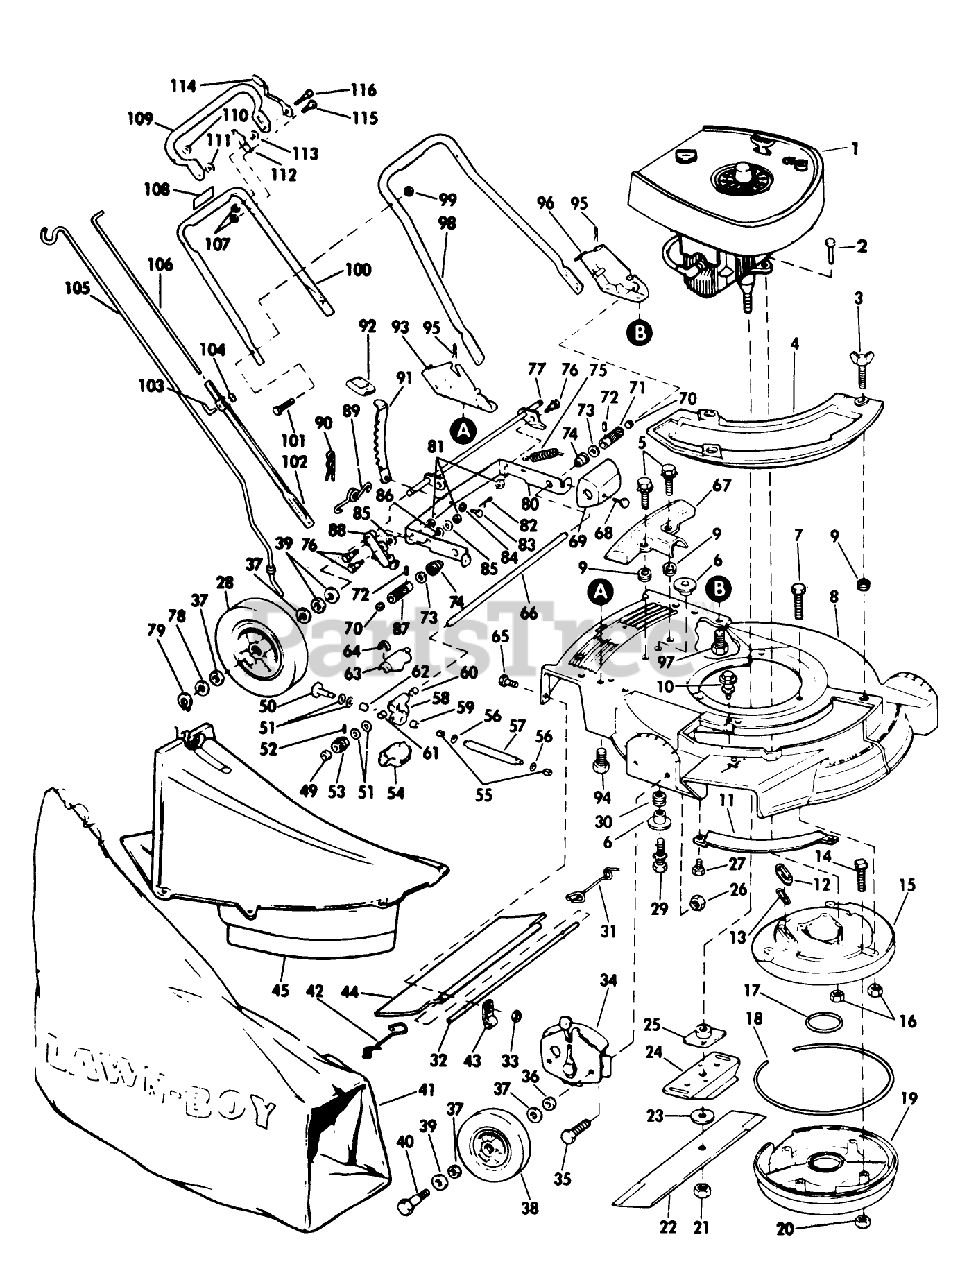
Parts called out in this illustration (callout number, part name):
2	BOLT F
3	WING SCREW LAWRE
5	SCREW SEMS TRM HEX HD
6	SPACER ECK PRES
7	SCREW V
11	BAR-TOE
12	SLEEVE
13	GASKET S
14	SCREW
16	NUT-LOCK F
18	Gasket Muffler (outside)
20	LOCKNUT E
21	NUT-BLADE
23	WASHER
25	PLATE AND COLLAR ASM
26	NUT-LOCK F
30	GROMMET
31	SPRIG T/SHLD ASOC
32	ROD 21" ADVANCE
33	LOCKNUT E
36	WASHER WROUGHT
37	WASHER
38	WHEEL & TIRE KIT
39	SPACER
40	BOLT WHEEL
41	89802 LB WHOLE GOODS
42	SPRING;TRAILING SHIELD RH
43	CLAMP ROD KMC
49	WASHER
51	THRUST WASHER
52	ROLL PIN
55	BUSHING
56	O Ring
62	NEEDLE BEARING
63	GEAR COVER UPPER
66	DRIVE SHFT TAG AY
67	COVER
69	GUARD
70	GREASE PLUG
72	PIN
75	SPRING
76	BOLT RB&W
78	SPACER
79	RET RING
81	STOP NUT
83	PIN
84	WASHER SPRING LAR
85	WASHER S
89	SPRING N.A.S
91	LEVER
92	KNOB
94	SCREW
95	HAIR PIN
97	SCREW
99	LOCKNUT E
101	SCREW
105	ROD GRASSBAG
106	ROD CONTROL
107	LOCKNUT E
111	WASHER M
114	KNOB & SPRING
116	BOLT RB&W
